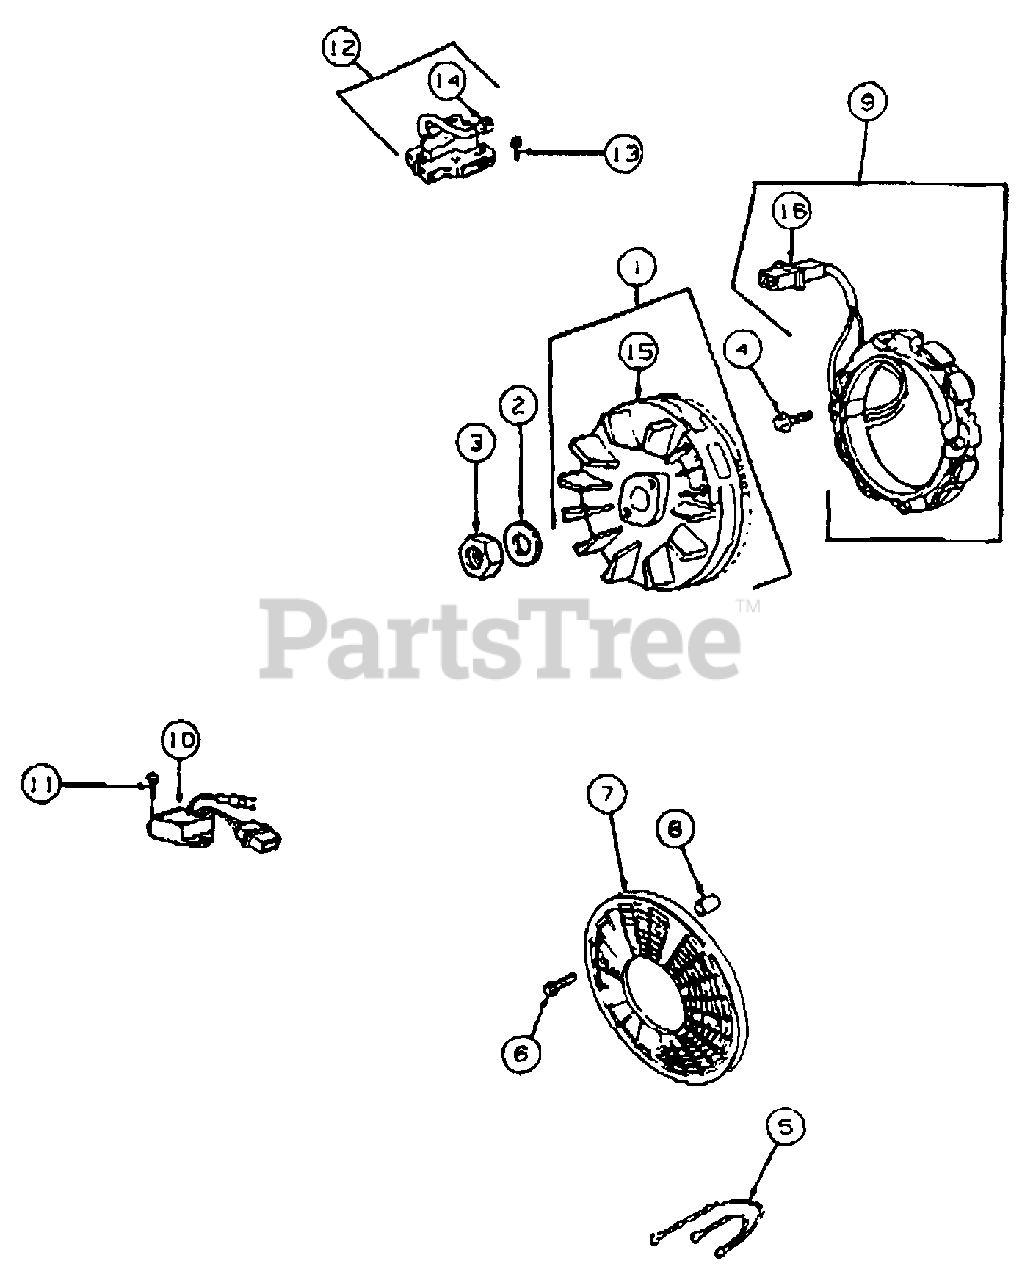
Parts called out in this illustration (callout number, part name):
1	Flywheel & Ring Gear
2	Washer, Spring
4	Screw, Mounting
5	Wire, Ground
6	Screw, Sems
7	Screen, Rotating
8	Spacer
9	Stator, 16 Amp
10	Regulator
11	Screw, Mounting
12	Armature
13	Screw, Mounting
14	Terminal
15	Gear, Flywheel Ring
16	Diode & Connector Assy
